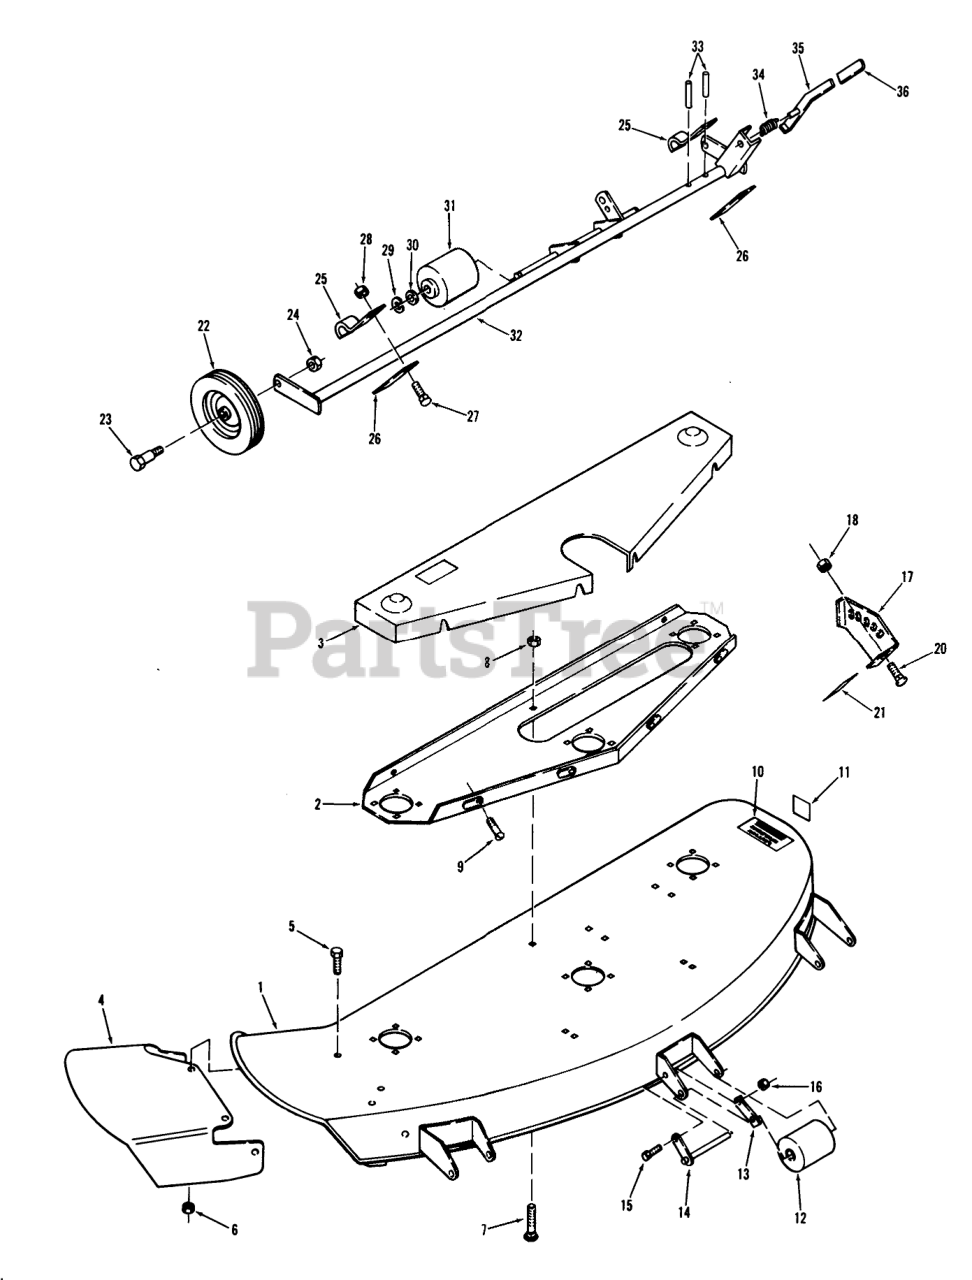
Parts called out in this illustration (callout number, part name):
1	ASSY-48 MOWER DEC R
1	Deck-42"
2	Support
3	COVER R
3	Belt Cover
4	Chute Extension
5	Bolt
6	Nut
7	Bolt-Carriage
8	NUT
9	Screw
9	Bolt
10	Decal
11	DECAL-WHEEL HORSE
12	Roller
13	SPRING ROLLER STOP
14	Roller Shaft
15	H H C S
16	Nut
17	LH QUADRANT R
17	Quadrant
18	NUT
20	Bolt
21	Decal Height Adjustment
22	Wheel
23	BOLT-SHOULDER
24	Nut
25	Machine Bolt
26	Bar
27	Bolt
28	NUT
29	E Ring
30	Washer
30	WASHER
31	Roller
32	Gage Wheel Support
32	Support Ass-y. Gage Wheel
33	PIN-SPIROL
34	SPRING-COMPRESSION
35	Lever
35	LEVER ASSY R
45	ASM-SUPPORT,IDLER
